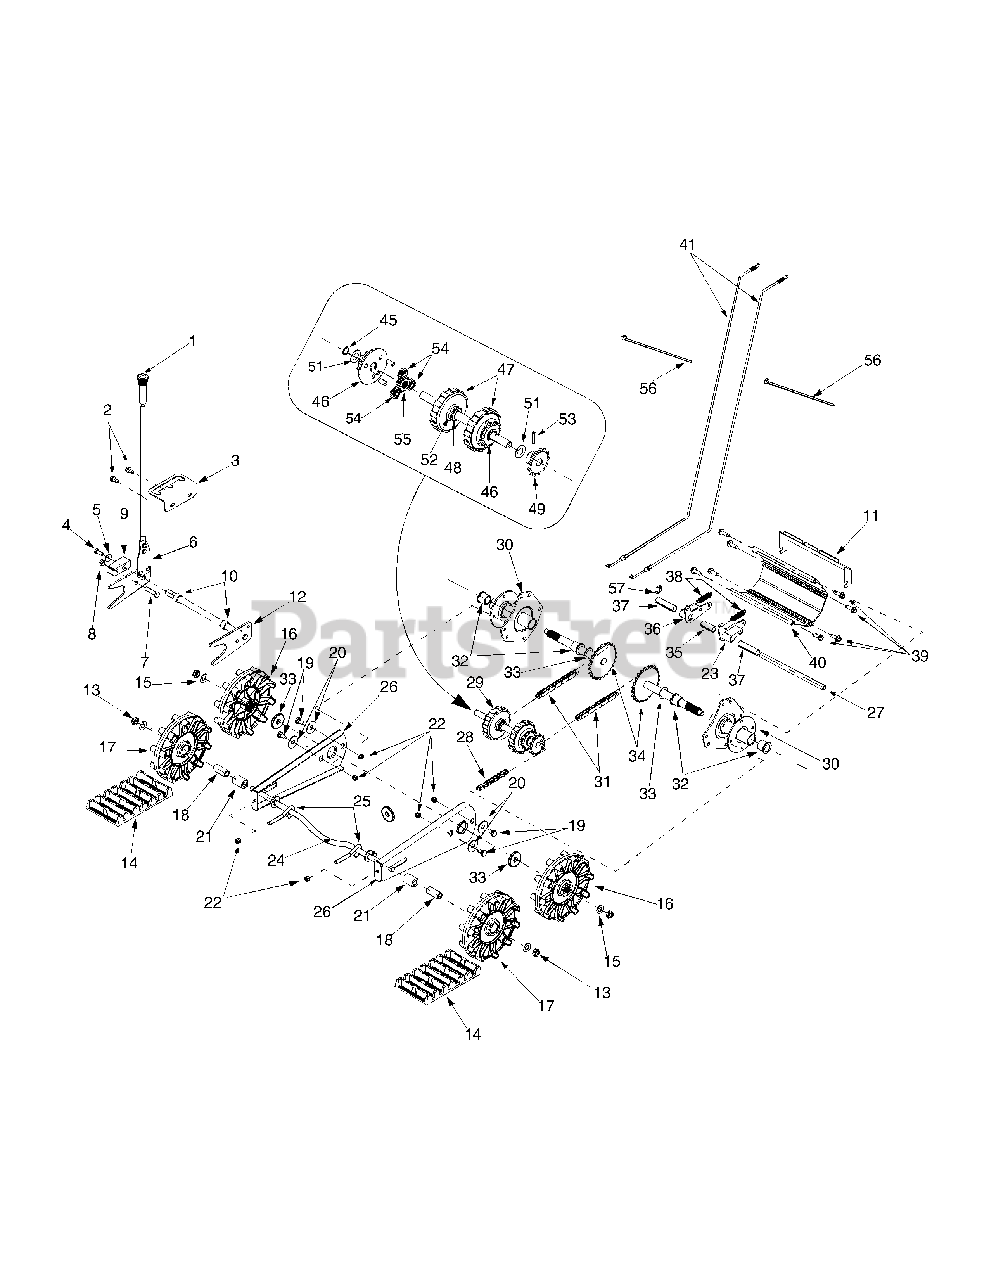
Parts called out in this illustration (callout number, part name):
2	Hex TT Screw 5/16-18 x .75
4	Hex Screw 5/16-24 x .75
5	Cupped Washer .345 ID x .88 OD x .060
6	Track Lock Handle Assembly
7	Hex Screw 3/8-16 x 1.50 Gr. 5
8	Hex Cent L-Nut 3/8-16
9	Lift Shaft Drive
13	Hex Ins Jam Nut 1/2-20
15	Flat Washer .53 ID x 1.00 OD x .06
16	Track Drive Wheel
17	Track Idler Wheel
18	Spacer .51 ID x .75 OD x 1.67
19	Shoulder Bolt .437 Dia x .180
20	Flat Washer .79 ID x 1.25 OD
21	Spacer .51 ID x 1.0 OD x 1.0
22	Flange Locknut 5/16-18 Gr. F, Nylon
23	LH Dog Assembly
25	J Bolt 5/16-18 x 3.0" Lg.
27	Actuator Shaft
28	#41 Chain .50 pitch X 30 links - End less
29	Track/Steering Shaft Ass’y
30	Track Hub Ass’y
31	#420 Chain 32 Links End less
32	Flange Bearing 3/4 ID x 15/16" Lg
33	Flat Washer .79 ID x 1.25 OD x .06
34	Axle Assembly
35	Spacer .49 x 1.67
36	RH Dog Assembly
37	Split Spacer .515 x .735 x 2.44
38	Extension Spring .47 OD x 2.03 Lg.
39	Hex Wash Hd Tapp Screw 5/16-18 x 1.00
40	Track Housing Ass’y
41	Steering Cable
45	Snap Ring
46	Carrier Ass’y
47	Ring Gear Ass'y
48	Snap Ring .625" shaft
49	13-Tooth Sprocket
51	Flat Washer .57 ID x 1.12 OD x .020
52	Flat Washer 5/8 ID x 1.0 OD x .030
53	Spring Pin Roll 3/16 Dia.
56	Cable Tie
